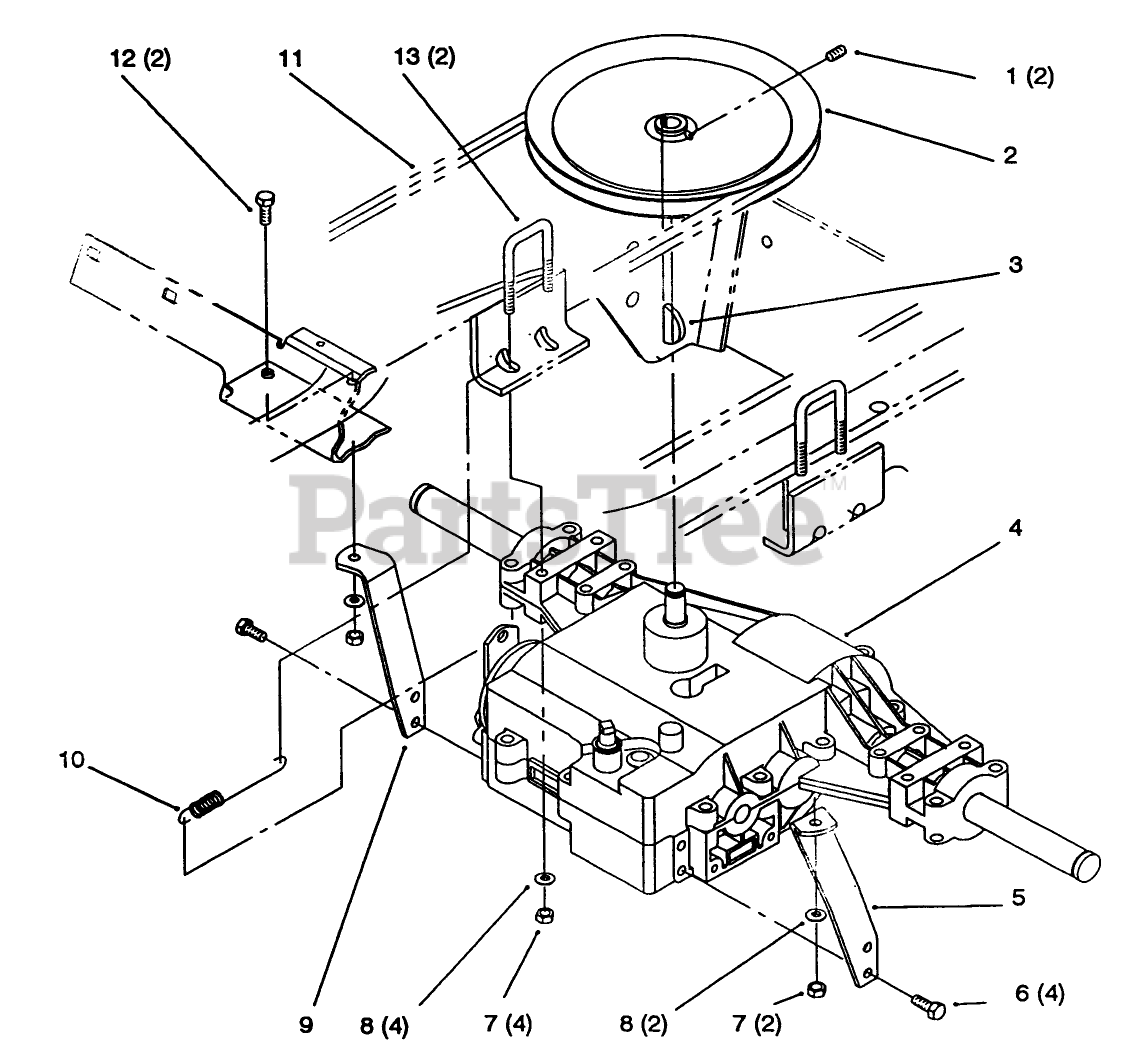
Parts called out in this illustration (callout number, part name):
1	SCREW-SQ HD SET
2	PULLEY-TRANS (GEAR)
3	KEY-HI-PRO
4	TRANSAXLE 820-024
5	STRAP - LH TORQUE
6	SCREW-HWHTF
7	NUT-LOCK, NI
8	WASHER-PLAIN
10	SPRING-EXTENSION
12	SCREW-HH
13	U-BOLT
